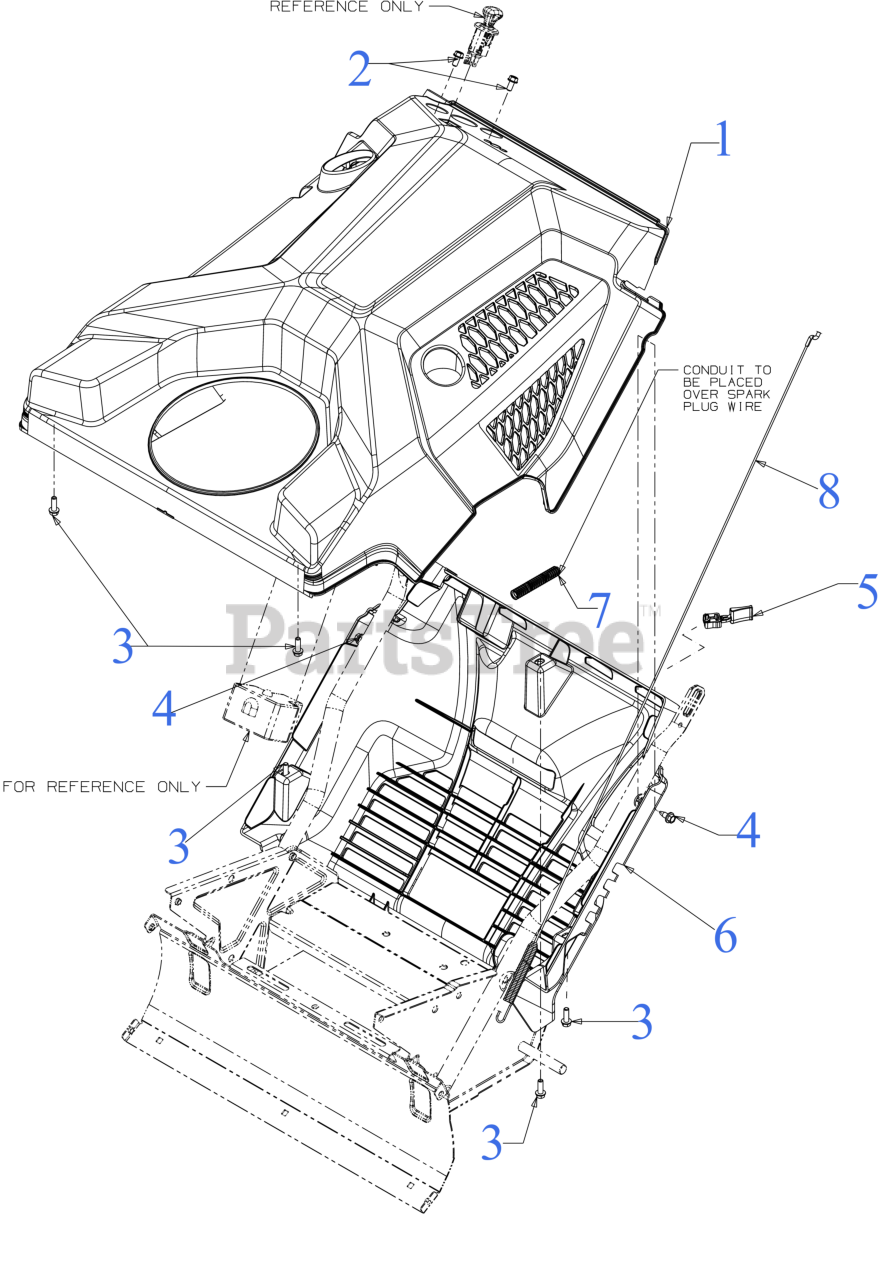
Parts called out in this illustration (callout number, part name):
1	COVER ASSEMBLY (G-STYLE) (RED) (W/O LIGHT)
2	HEX SCREW 1/4-15 x .50
3	SCREW 1/4-15 x .750
4	SCREW 1/4-20X.625
5	CHOKE EXTENION LEVER
6	BOTTOM COVER
7	CONVOLUTED CONDUIT
8	AUGER CLUTCH CABLE 37.05"
